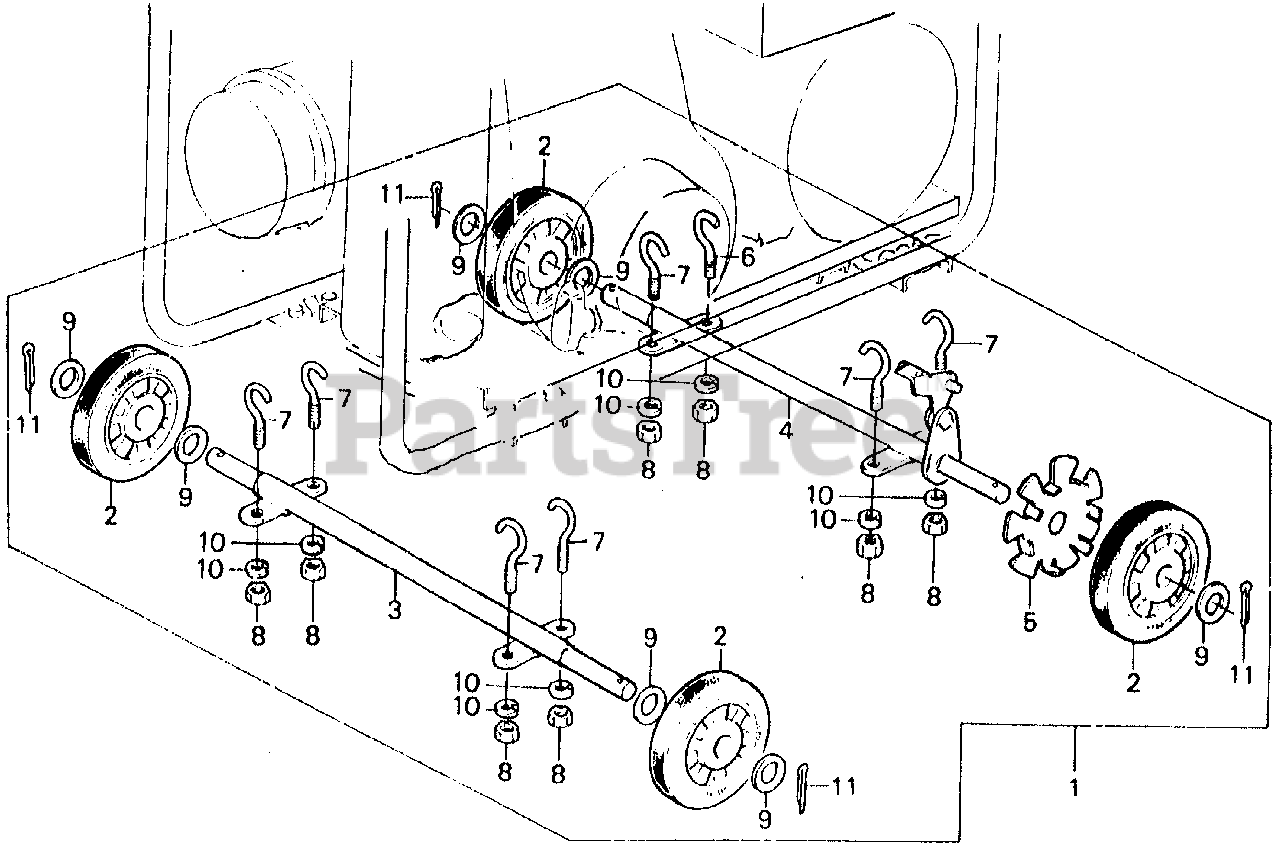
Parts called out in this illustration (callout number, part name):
1	WHEEL KIT Use up to Frame SN 1109398.
1	WHEEL KIT Use from Frame SN 1109399.
2	WHEEL
3	SHAFT A, WHEEL
4	SHAFT B, WHEEL Use up to Frame SN 1109398.
4	SHAFT B, WHEEL Use from Frame SN 1109399.
5	PLATE, LOCK
6	BOLT A, HOOK
7	BOLT B, HOOK
8	NUT, HEX. (8MM)
9	WASHER, FLAT (20MM)
10	WASHER, SPRING (8MM)
11	PIN, COTTER (4.0X30)
